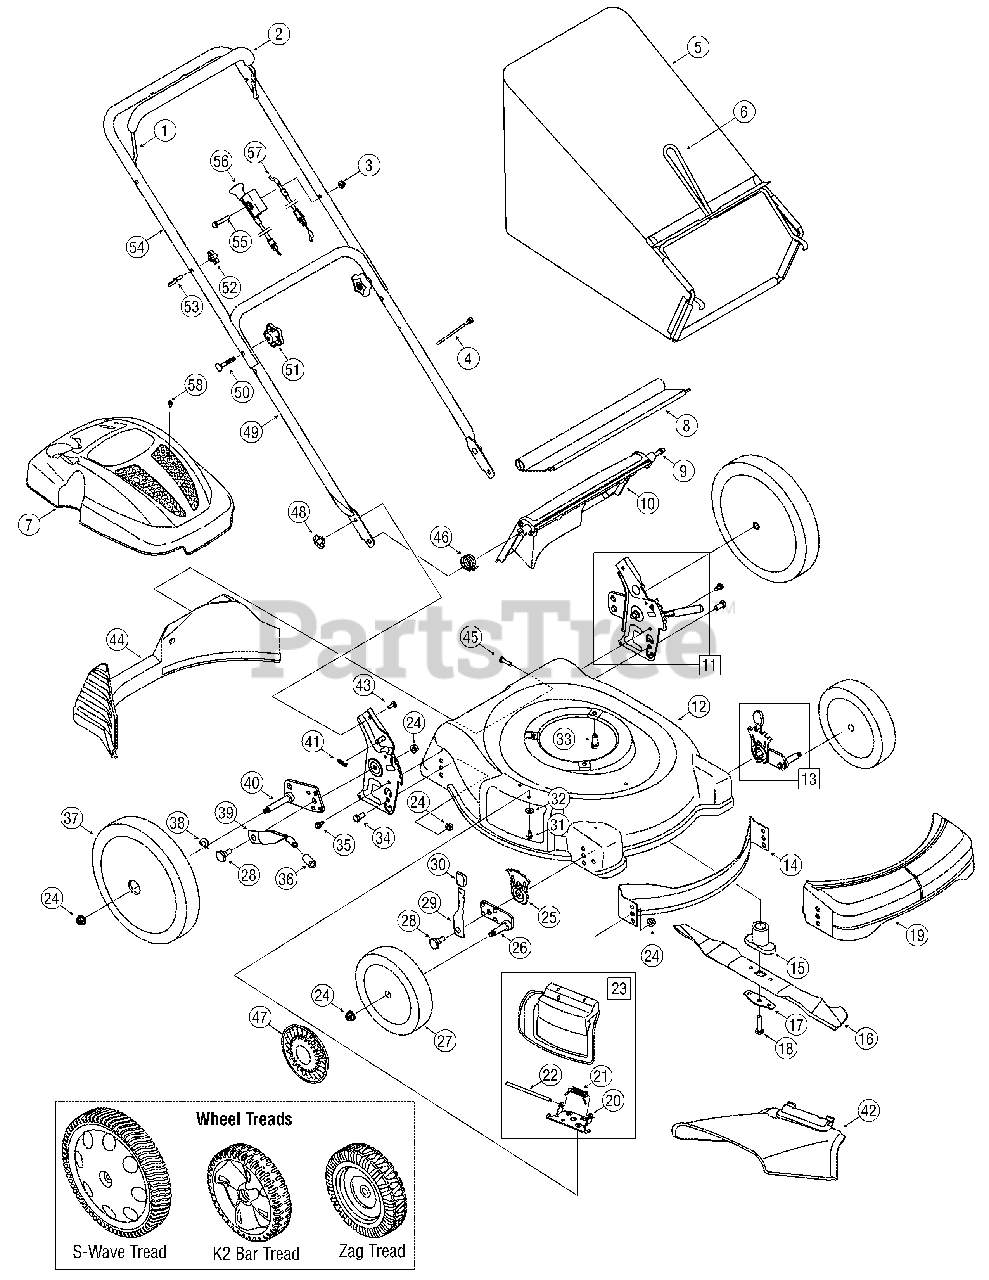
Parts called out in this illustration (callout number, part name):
2	Bail Cover If Equipped
3	Flange Lock Nut 1/2-20
4	Cable Tie
5	Grass Bag Assembly
7	Engine Shroud
8	Trailshield
9	Pivot Rod
10	Rear Discharge Door
11	Rear Handle Brkt. Assy. - LH
11	Rear Handle Brkt. Assy. - RH
13	Front Height Adj. Assy - RH
14	Front Baffle
15	Blade Adapter
16	21-inch Mulching Blade
17	Bell Blade Support
18	Hex Screw, 3/8-24 x 2.5
19	Deck Cover If Equipped
20	Chute Deflector Adapter
21	Torsion Spring
22	Hinge Pin
23	Hinged Mulch Plug Assembly
24	Flange Lock Nut 3/8-16
25	Height Adjustment Plate
26	Front Pivot Arm Assembly - RH
26	Front Pivot Arm Assembly - LH
27	Front Wheel, 7 x 1.8, K2 Bar
28	Shoulder Screw, .5D x .434
29	Front Spring Lever
30	Height Adjust Knob
31	TT Screw, 1/4-20 x .500
32	Bell Washer
33	TT Screw, 3/8-16 x 1.0
34	Hex Screw, 3/8-16 x .75
35	TT Screw, 1/4-20 x .625
36	Foam Grip
37	Rear Wheel, 12 x 1.8, K2
38	Spring Washer If Equipped
39	Rear Hi-Wheel Spring Lever
40	Rear Pivot Arm Assy - RH
40	Rear Pivot Arm Assy - LH
41	Hairpin Clip
42	Side Discharge Chute
43	Carriage Bolt ,1/4-20 x .75
44	Rear Baffle
45	Screw HL, 1/4-15 x 1.00
46	Torsion Spring - RH
47	Hub Cap, Radial Spoke
48	Wing Nut
50	Carriage Bolt, 5/16-18 x 2
51	Star Knob
52	Handle Knob
53	Eye Bolt
55	Hex Screw, 1/4-20 x 1.50
56	Cable, Choke 38-inch
57	Cable, ERS 48-inch
58	Machine Screw M4-.7x10.
